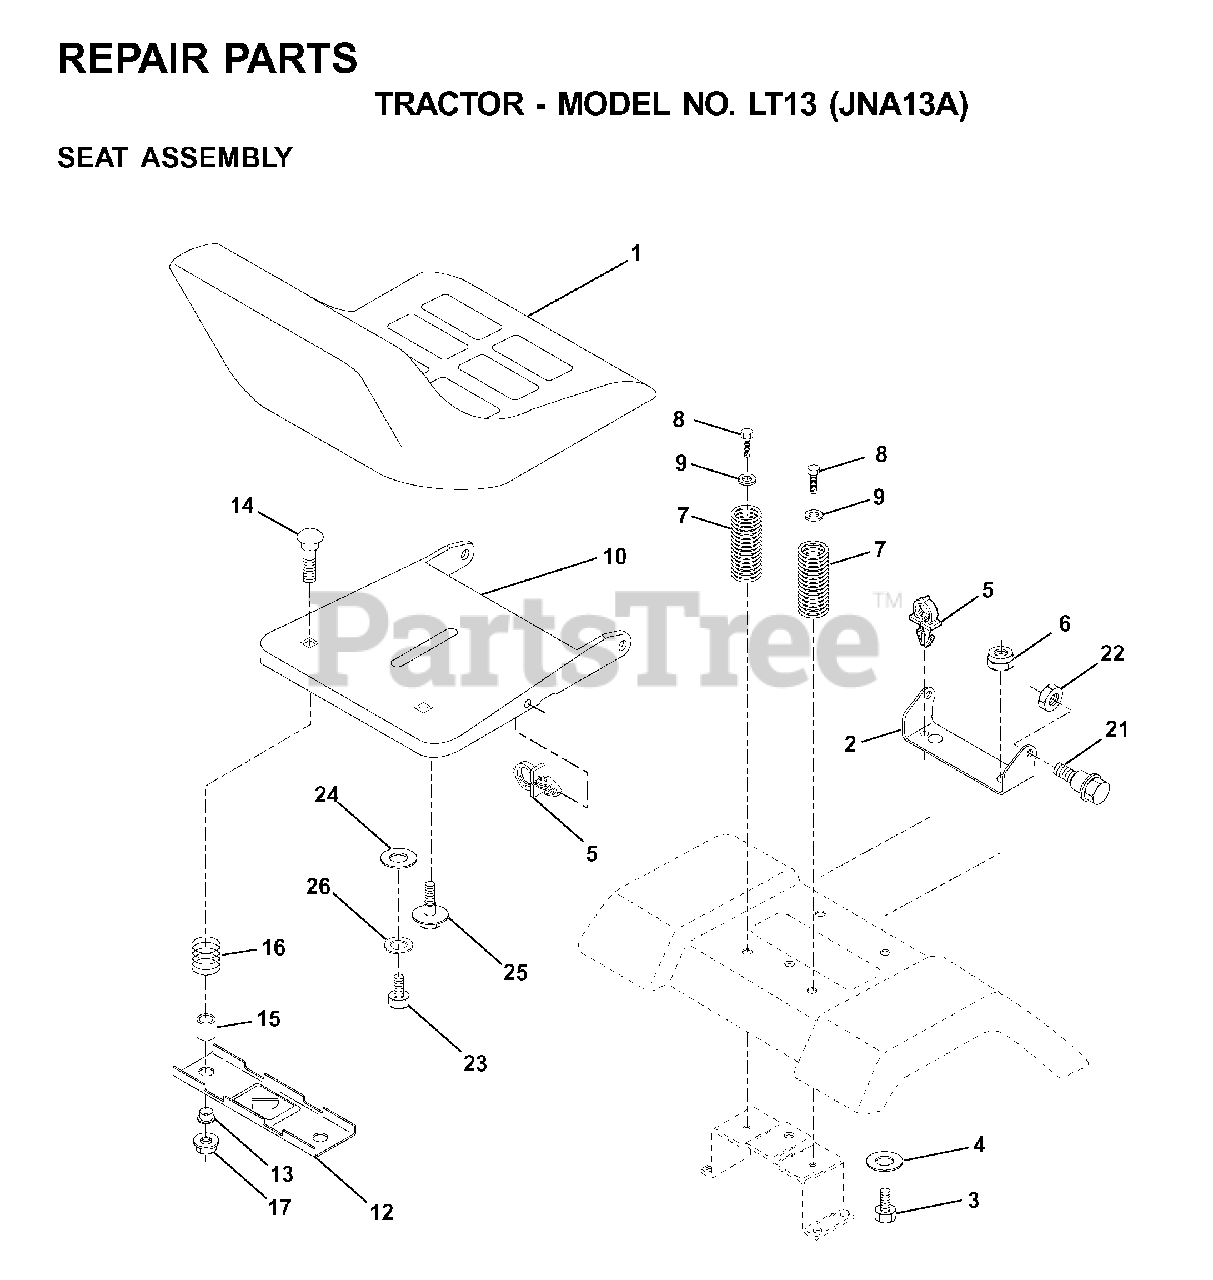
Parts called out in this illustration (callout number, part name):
1	SEAT
2	SEAT PIVOT BRKT
4	WASHER PM
5	PUSH CLIP
6	NUT
7	SPRING COMPRESSION
8	SCREW 3/8-16X1
9	WASHER
10	PAN, SEAT
12	BRKT SWITCH
14	BOLT.ROUND.HEAD.SQUARE.NECK
15	SPACER SPLIT 28X.96
17	NUT T
21	BOLT.SHOULDER.5/16-18
22	NUT.71038.31-18.HEX.NYLOCK
23	BOLT.HEX.BLACK
25	BOLT,SHOULD
26	LOCKWASHER
